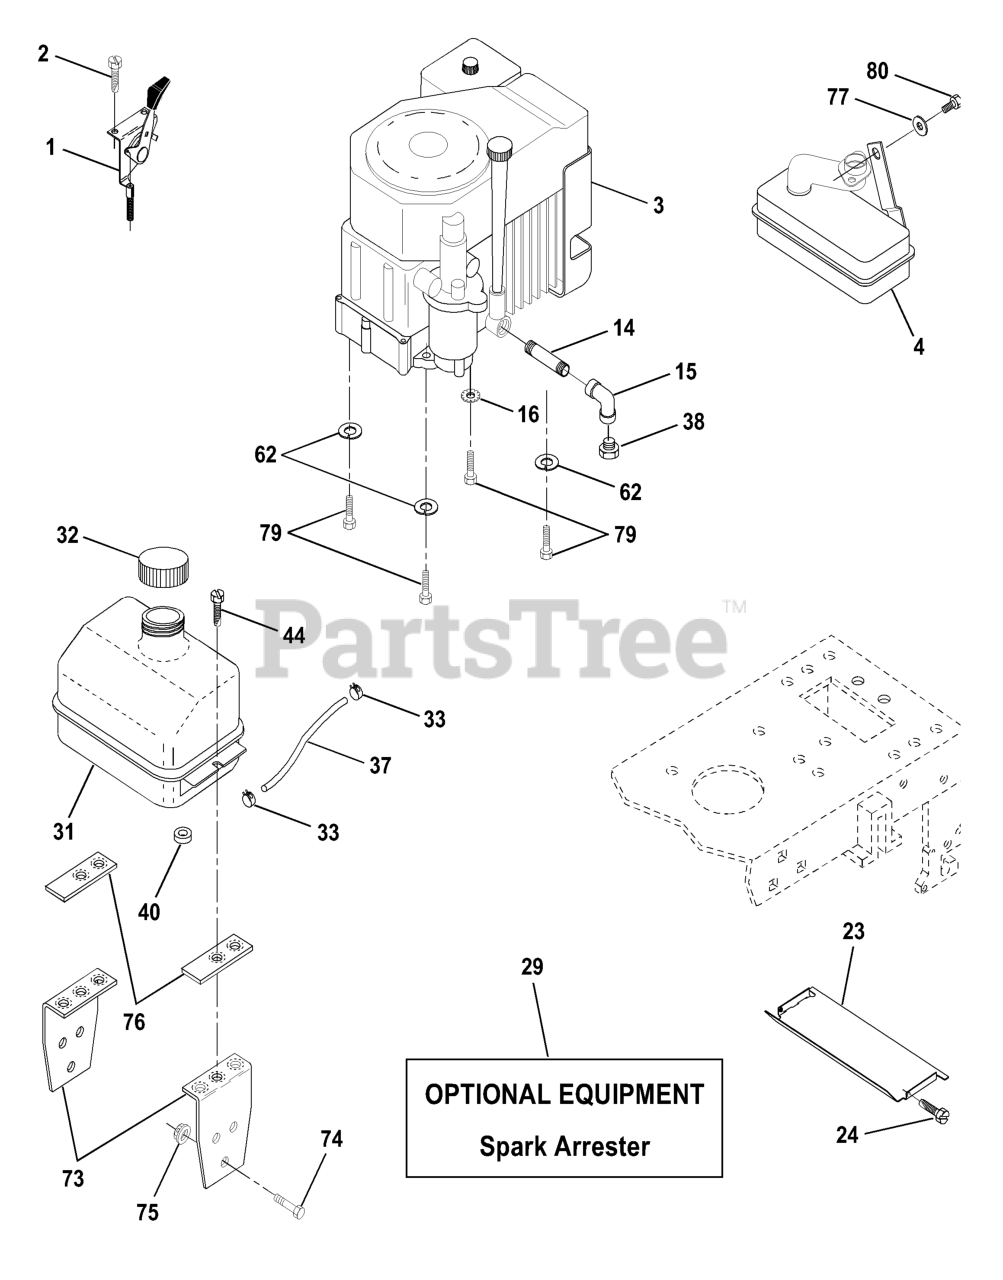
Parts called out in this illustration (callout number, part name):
1	THROTTLE CONTROL
2	SCREW LT
4	MUFFLER LT 12.5
14	Nipple Pipe 3/8 Npt X 3-1/2"
15	ELBOW
21	SNAP BUSHING T
23	HEAT SHIELD
29	KIT.SPARK ARRESTOR 794945 B&S
31	TANK FUEL LT
32	FUEL CAP
33	HOSE CLAMP
37	FUEL LINE T
38	Plug Oil Drain (Order from Engine Mfg.)
40	SNAP BUSHING T
44	SCREW
45	Bolt, Hex (Order from Engine Mfg.)
62	WASHER.LOCK.HVY.HLCL.SPR.5/16
63	WASHER EXT TOOTH LOCK 5/16
73	BRACKET FUEL TANK T
74	BOLT
75	NUT
76	CLAMP, FUEL TANK T
77	WASHER
79	BOLT, HEX
80	Bolt, Fin Hex 5/16-18 X 5/8
